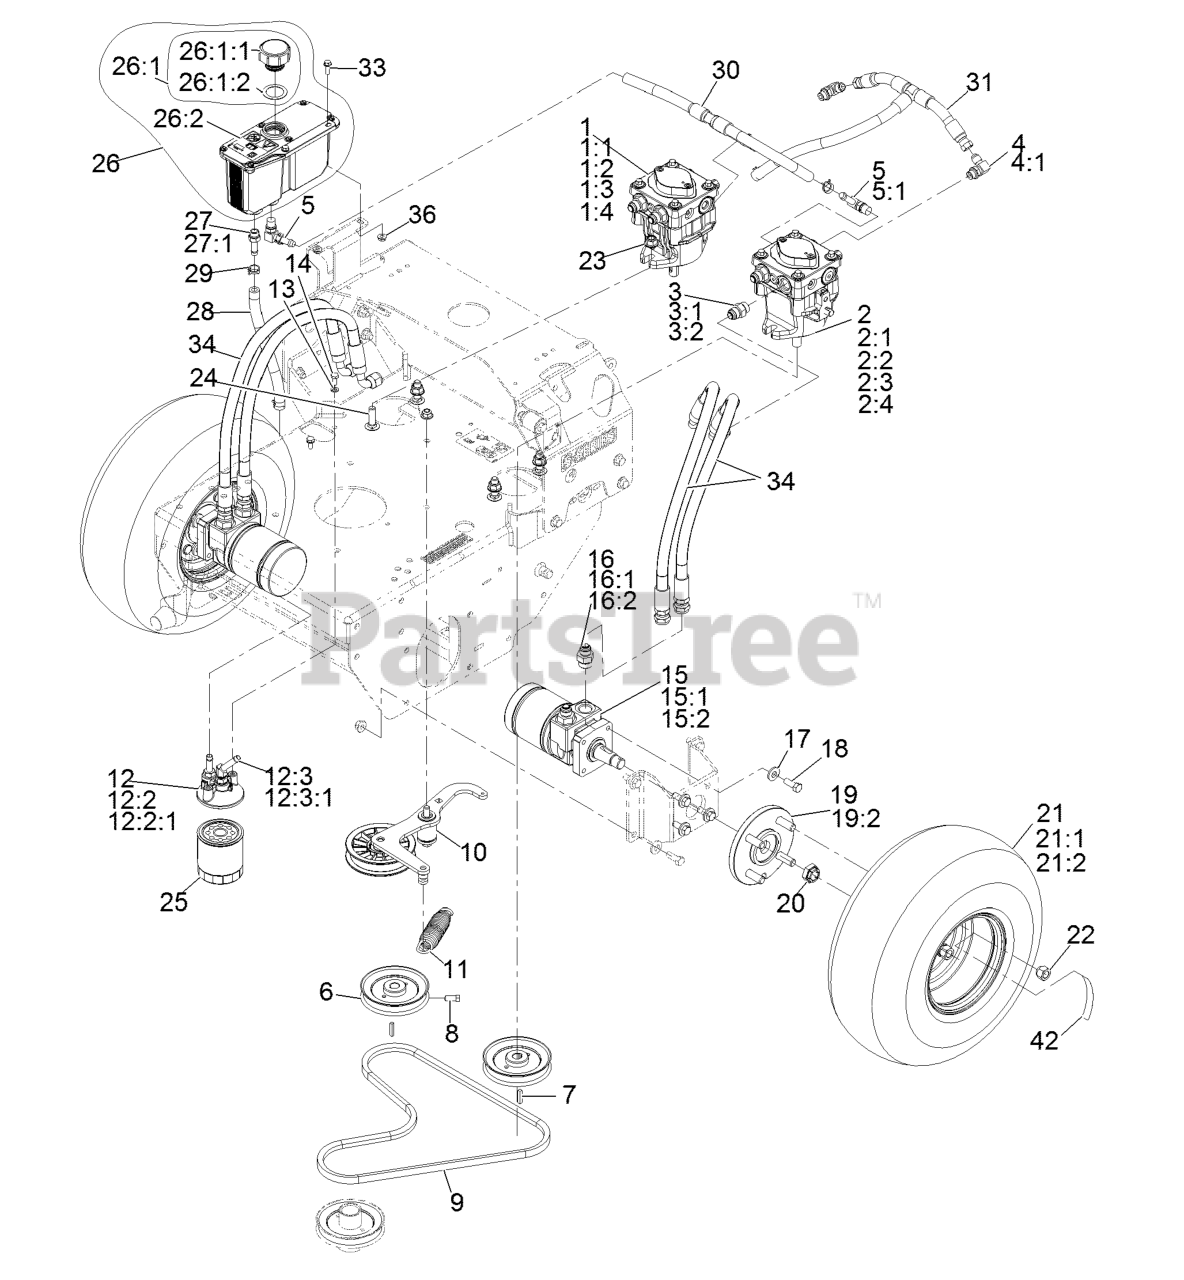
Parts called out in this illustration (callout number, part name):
1	RH HYD Pump ASM
1:1	Input Shaft Kit
1:2	Bearing-Thrust
1:3	Cylinder Block Kit
1:4	Seal Overhaul Kit
2	LH HYD Pump ASM
2:1	Input Shaft Kit
2:2	Bearing-Thrust
2:3	Cylinder Block Kit
2:4	Seal Overhaul Kit
3	Adapter-Straight
3:1	O-Ring-SAE #8
3:2	O-Ring-37 Flare #8
4	Fitting-Elbow, 90 DEG
4:1	O-Ring
5	Fitting-Elbow, 90
5:1	O-Ring
6	Sheave ASM
7	Key-5Mm X 5Mm X 25Mm
8	Screw-Set, SQH 5/16-18 X 3/4
9	Belt
10	ASM, Pump Idler
11	Spring-Extension
12	ASM, Filter Head
12:2	Adapter-Straight
12:2:1	O-Ring
12:3	Fitting-Barbed, 45 DEG
12:3:1	O-Ring
13	Washer-Lock 1/4 Heavy
14	Screw-HH 1/4-20 X 5/8
15	HYD Motor ASM
15:1	Seal Kit
15:2	Bearing And Seal Kit
16	Adapter-Straight
16:1	O-Ring
16:2	O-Ring-37 Flare #8
17	Washer-Spring Disc 3/8
18	Screw-HH 3/8-16 X 1
19	Wheel Hub ASM
19:2	Stud-Wheel
20	Nut-Lock
21	Wheel And Tire ASM
21:1	Tire-Turfmaster
21:2	Rim-Wheel
22	Nut-Lug 1/2-20
23	Nut-HF, NI
24	Bolt-Carriage 7/16-14 X 1 1/2
25	Element, Oil Filter
26	ASM, HYD Reservoir
26:1	Reservoir-HYD
26:1:1	Cap-Reservoir, HYD
26:1:2	Gasket-Cap
26:2	Decal-Warning
27	Adapter-Straight
27:1	O-Ring
28	Hose-Charge
29	Clamp-Hose 11/16
30	Hose-Case Drain
31	Hose-Charge
33	Screw-Machine 1/4-20 X 3/4
34	HYD Hose ASM
36	Nut-Whizlock 1/4-20
42	Decal-Torque Wheel Lug-Hub
